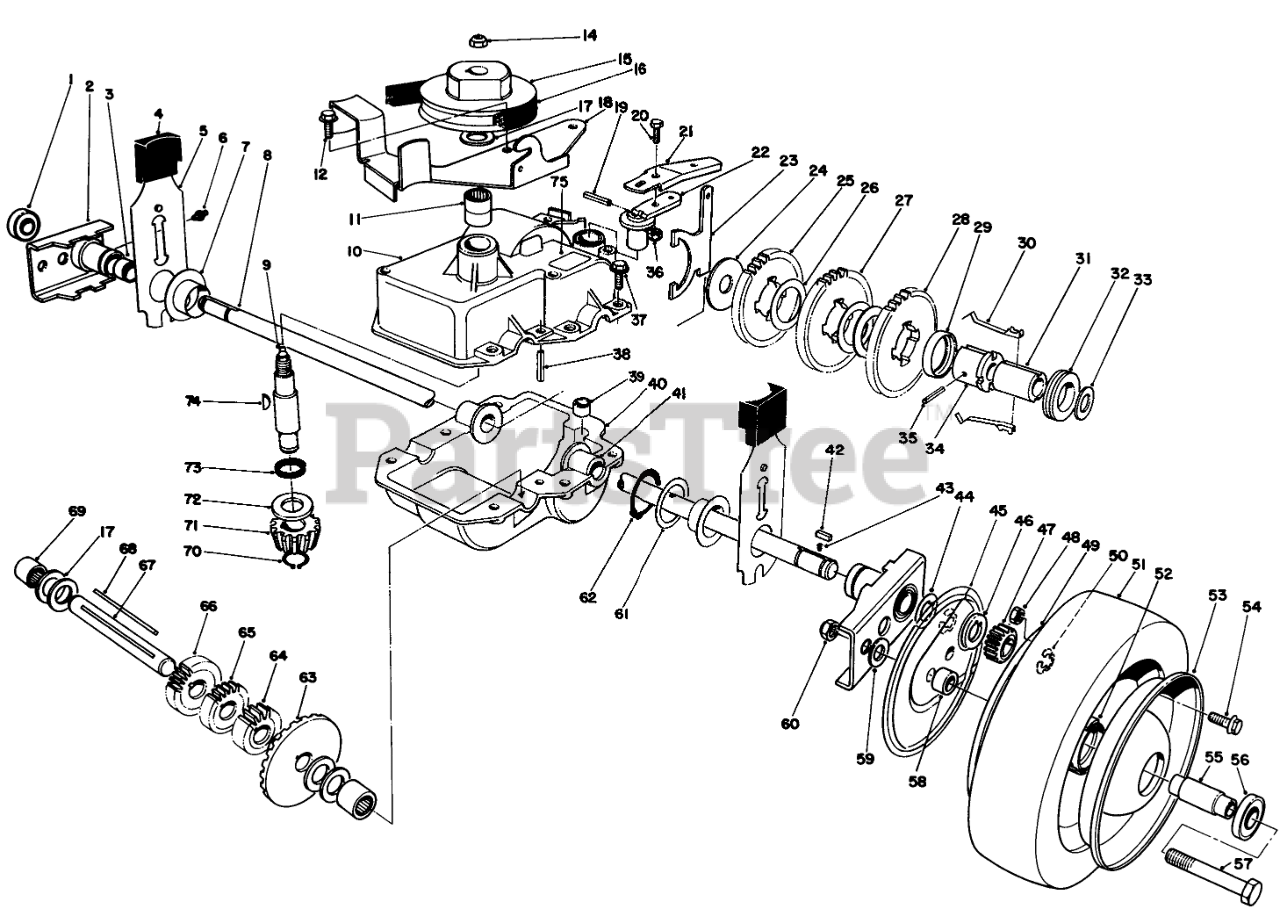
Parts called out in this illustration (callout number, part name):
1	BEARING-WHEEL
2	Pivot Arm Assembly (Incl. Ref. #1, 3 & 6)
3	BUSHING
4	KNOB-ARM
5	REAR SPRING ARM ASM
6	FITTING-GREASE
7	CAP-END
8	Shaft-Output
9	INPUT SHAFT ASM
10	Upper Case Assembly (Incl. Ref. #11 & 73)
11	BEARING-NEEDLE
12	SCREW
14	NUT-HEX
15	PULLEY
16	V-BELT
17	WASHER-THRUST
18	Belt Guide Bracket
19	PIN-COIL
21	SHIFT LEVER COVER
22	LEVER-SHIFT
23	Shift Yoke
24	WASHER
25	GEAR-38T
26	WASHER
27	GEAR-42T
29	RETAINER-KEY
30	KEY-SHIFT
31	SLEEVE
32	COLLAR-SHIFT
33	WASHER-PLAIN
34	SLEEVE-GEAR
35	PIN-GROOVE
36	NUT-LOCK, NI
37	SCREW-HWHTF
38	ROLL PIN 3/16 X 1 IN
39	BUSHING-YOKE
40	Case-Lower
41	BUSHING
42	KEY RECTANGULAR
43	SPRING-COMPRESSION
44	WASHER-THRUST, OUTER
45	WHEEL COVER
46	WASHER-THRUST, OUTER
47	GEAR-PINION
48	NUT-LOCK, NI
49	Wheel-Half
50	RING-RETAINING
52	HUB-BEARING
53	Wheel-Half
54	SCREW-HHF
55	SPACER-BEARING
56	BEARING-WHEEL
57	SCREW-HH
58	SPACER-WHEEL
59	WASHER
60	NUT-LOCK, CONE
61	WASHER
62	RING-RETAINING
63	BEVEL GEAR
64	GEAR-12T
65	GEAR-14T
66	GEAR-18T
67	SHAFT-INTERMEDIATE
69	BEARING-NEEDLE, CLOSED
70	RING-RETAINING
71	PINION-BEVEL
72	WASHER-THRUST
74	KEY-WOODRUFF
